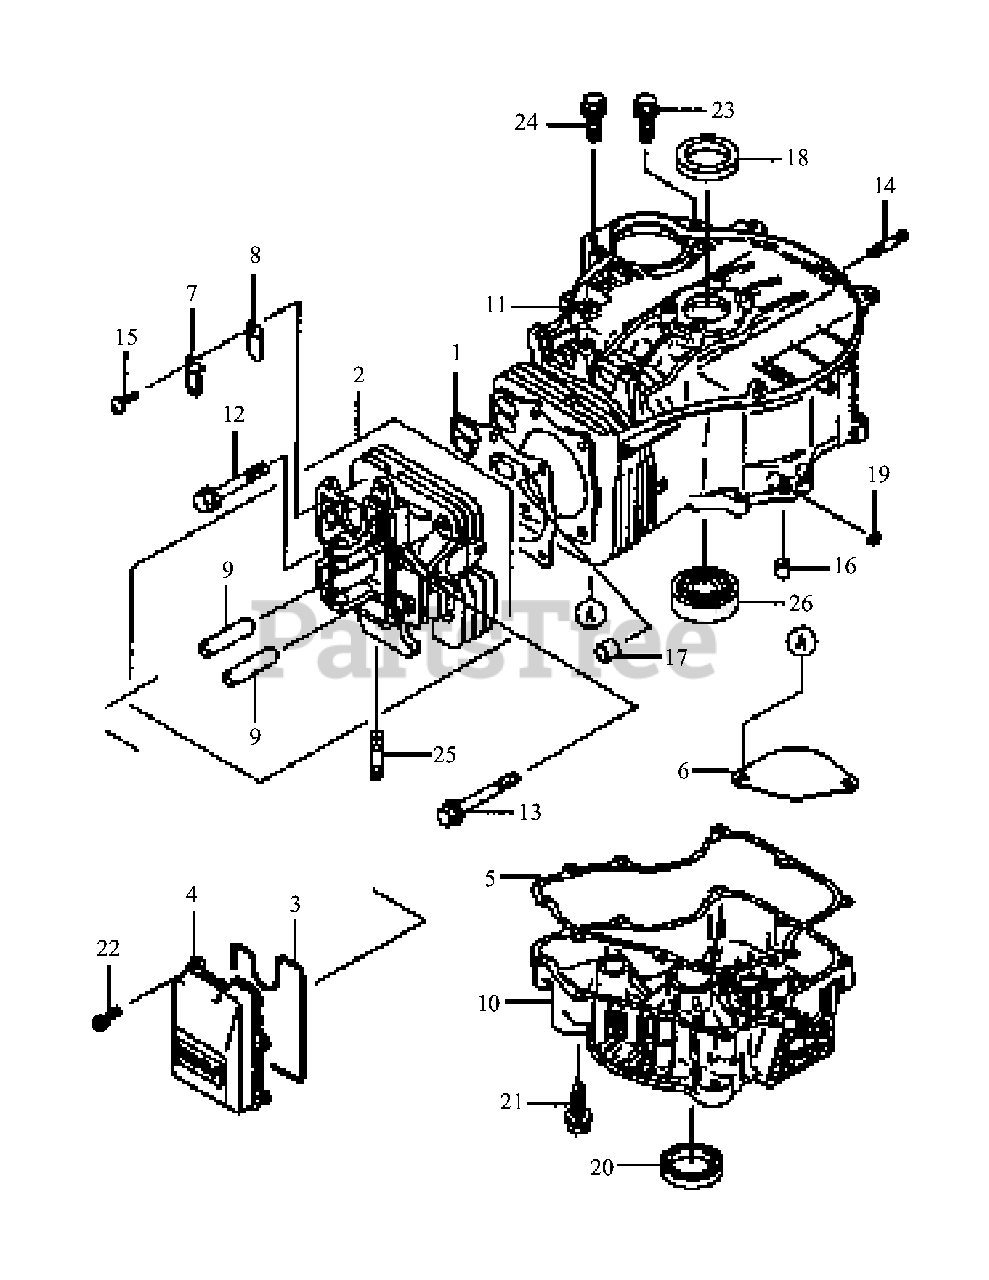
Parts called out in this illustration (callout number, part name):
2	Head, Cylinder
3	Gasket, Rocker Case
5	Gasket, Crankcase
10	Cover, Crankcase
22	Bolt, Flange
23	Bolt, Flange
24	Bolt, Flange
26	Bearing, Ball
